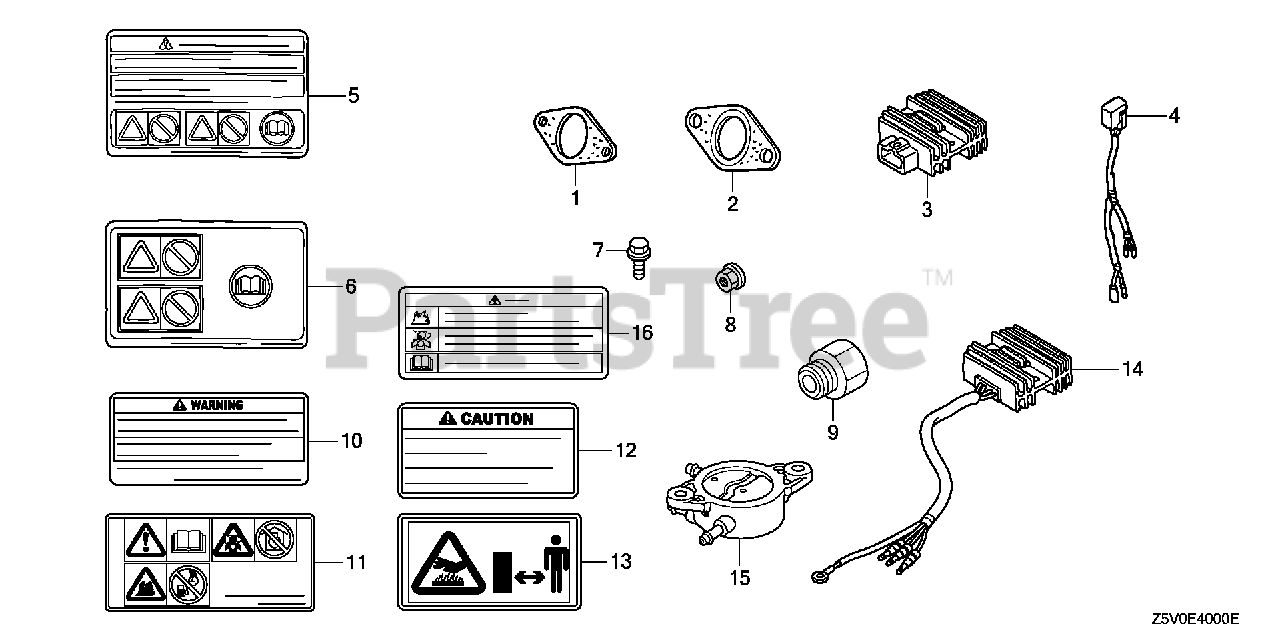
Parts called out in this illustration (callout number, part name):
10	MARK, OPERATOR CAUTION (ENGLISH)(MADE IN THAI)
10	MARK, OPERATOR CAUTION (FRENCH)(MADE IN THAI)
12	MARK, EX. CAUTION (ENGLISH)
12	MARK, EX. CAUTION (FRENCH)
